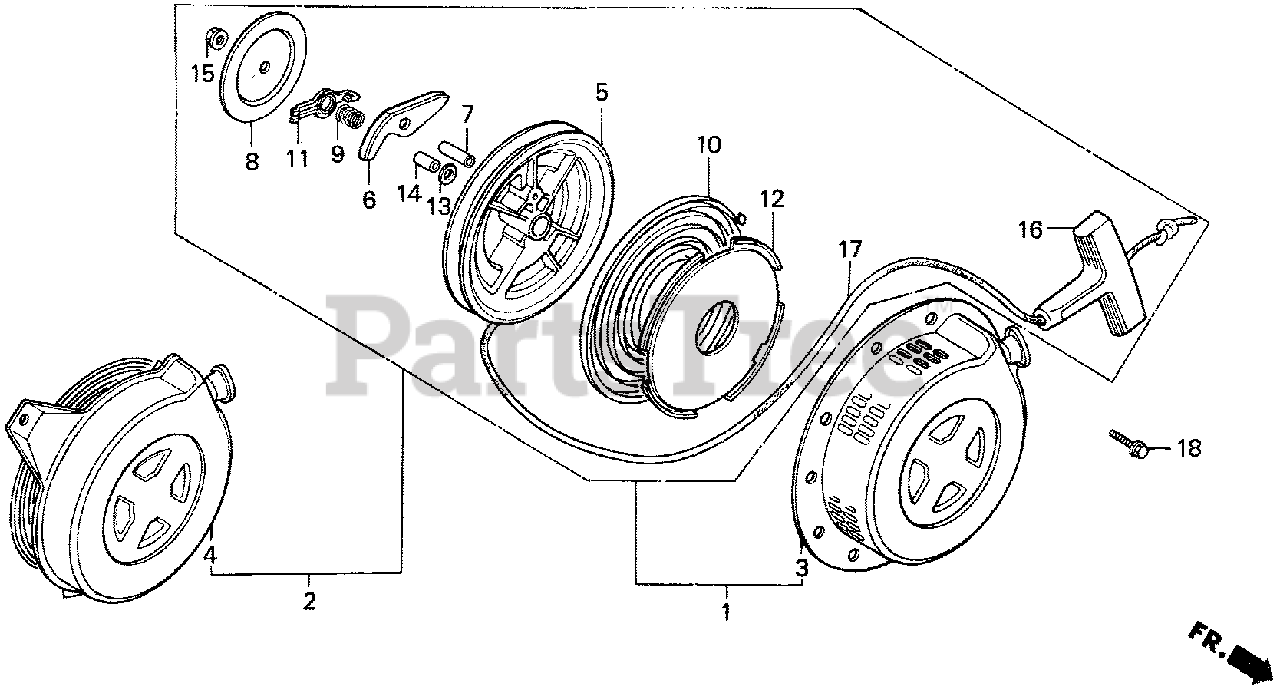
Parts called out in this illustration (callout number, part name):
1	STARTER ASSY., RECOIL *R8* (BRIGHT RED)
3	CASE, RECOIL STARTER *R8* (BRIGHT RED)
5	PULLEY, RECOIL STARTER
6	RATCHET, STARTER
7	PIN, STARTER RATCHET
8	PLATE, FRICTION
9	SPRING, FRICTION
10	SPRING, RECOIL STARTER
11	GUIDE, RATCHET
12	CASE, RECOIL STARTER SPRING
13	WASHER, STARTER
14	SHAFT, SUB
15	NUT
16	KNOB, RECOIL STARTER
17	ROPE, RECOIL STARTER (#5X59") (NA USE ALT:08550-ZG921-11)
18	BOLT, FLANGE (6X8)
18	BOLT, FLANGE (6X10)
